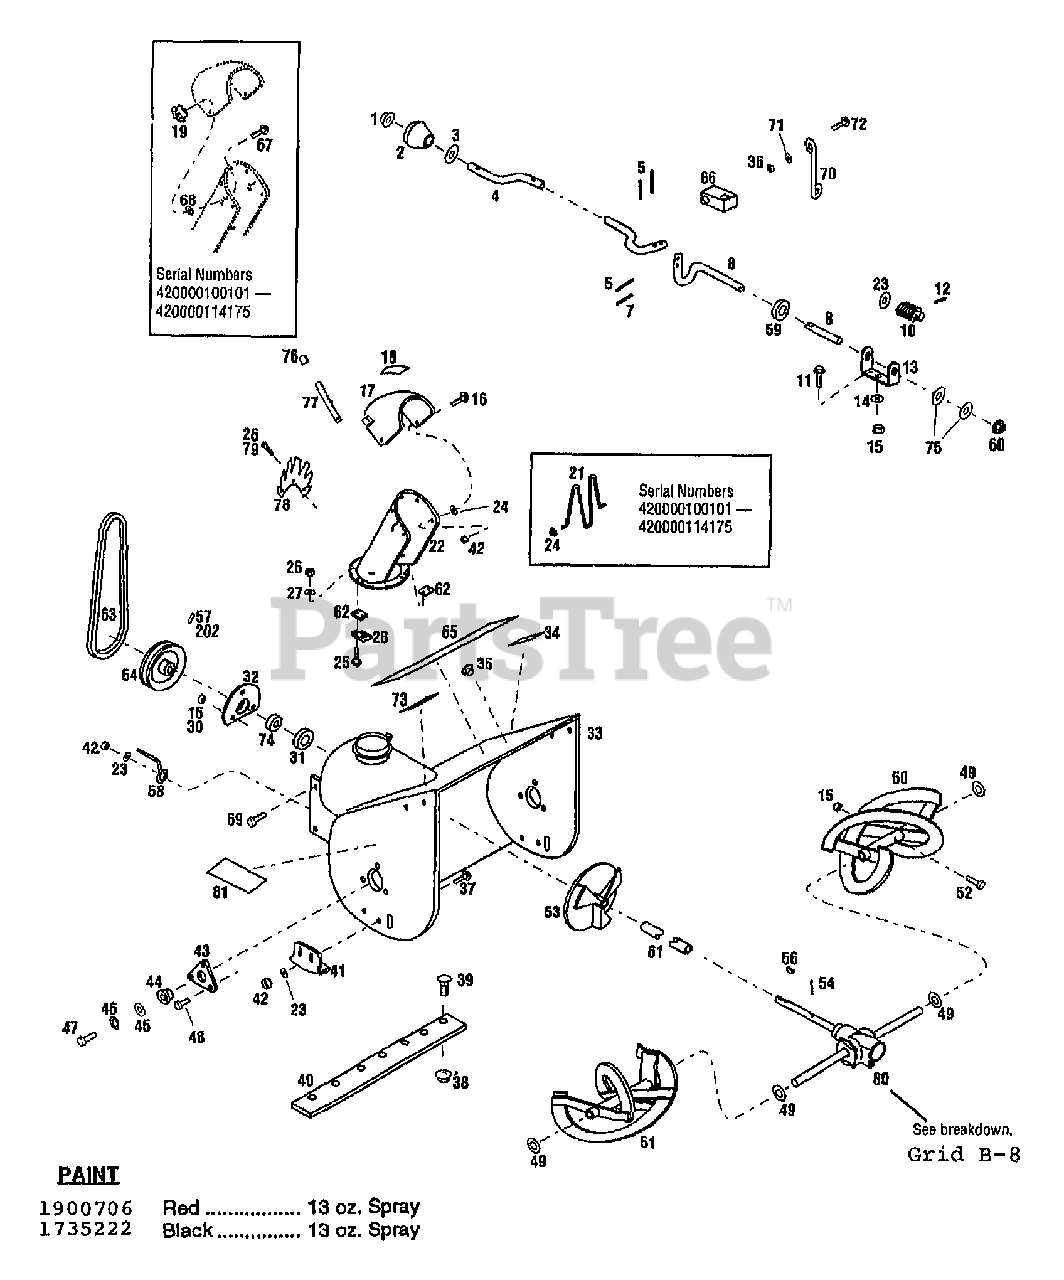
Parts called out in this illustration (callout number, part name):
1	NUT-PUSH 3/8 ZP
2	KNOB
3	WASHER-FLAT .375DIA
4	CRANK-CHUTE CONTROL
5	PIN-COTTER .093X.625
7	PIN-ROLL 1/8 X 3/4
8	SHAFT-CHUTE CNTRL USE1771769 @
8	SHAFT-CHUTE CONTROL
10	GEAR-WORM LH
11	SCR-HFLK 5/16-18X.75 ZP
12	PIN-DRIVE .09X.75
13	SUPPORT-GEAR
14	WASHER-FLAT 5/16 SAE
15	NUT-TOP/LK 5/16-18 ZP
16	SCR-HH 3/8-16X.75 G5 ZP
17	ASSM-DISCHARGE CAP
18	DECAL-WARNING
21	GUARD-CHUTE
22	ASSM-CHUTE
23	WASHER-FLAT 3/8 SAE
24	NUT-PUSH 3/16
25	SCR-HW M10-24X.88 EXTTOOTH
26	NUT-H/LK M10-24 NYLOCK
27	WASHER-.505X.22X.05
28	CLIP-HOLD DOWN
30	SCR-HH 5/16-18X.63 G5
31	BEARING-BALL
32	RETAIN-BEARING
33	ASSM-HOUSING
34	DECAL-WARNING
36	NUT-HT LK 1/4-20
37	BOLT-3/8-16 X 3/4
38	NUT-HFLK 5/16-18 ZP
39	SCR-CARR 5/16-18X.50 G5 ZP
40	BLADE-SCRAPER
41	RUNNER-SKIP
42	NUT-LOCK 3/8-16
43	SUPPORT-BEARING
44	BUSHING-FLANGE
45	WASHER-1/2 FLAT
46	WASHER-LK .5
47	SCR-HH 1/2-13X.75 G5 ZP
48	SCR-HH 1/4-20X.625 G5 ZP
49	WASHER-SPEC
50	ASSM-AUGER BLADE LH
51	ASSM-AUGER BLADE RH
52	SCR-SHEAR 5/16-18X1.75
53	ASSM-IMPELLER
54	PIN-ROLL 1/4 X 1-1/4
56	KEY-HI PRO .187X.75
57	SCR-SET SQ 5/16-18X5/8
58	GUIDE-BELT
59	BUSHING-NYLON
60	NUT-HF/LK 3/8-16
61	SLEEVE
63	BELT-V 36.00
64	SHEAVE-AUGER DRIVE
65	DECAL-LOGO
66	BLOCK-SWIVEL NYLON
67	SCR-CARR 5/16-18X1.0 G2 ZP
68	WASHER-.986X.437X.083 ZP
69	SCR-HFLK 5/16-18X.75
70	SUPPORT-CHUTE CRANK
71	WASHER-FLAT 1/4 SAE
72	SCR-HH 1/4-20X1.5 G5ZP
73	DECAL-AMERICAN LEGEND-LRG
74	SHIM-1.75X1.26X.02
75	BUSHING-NYLON
76	GRIP-VACUCUT
77	LEVER-ADJUSTING
78	DEFLECTOR-CHUTE
79	SCR-TR HD 10-24X.375
80	ASSM-GEAR CASE
81	DECAL-HOUSING SIDE
202	LOCTITE-242 (.5 ML TUBE)
